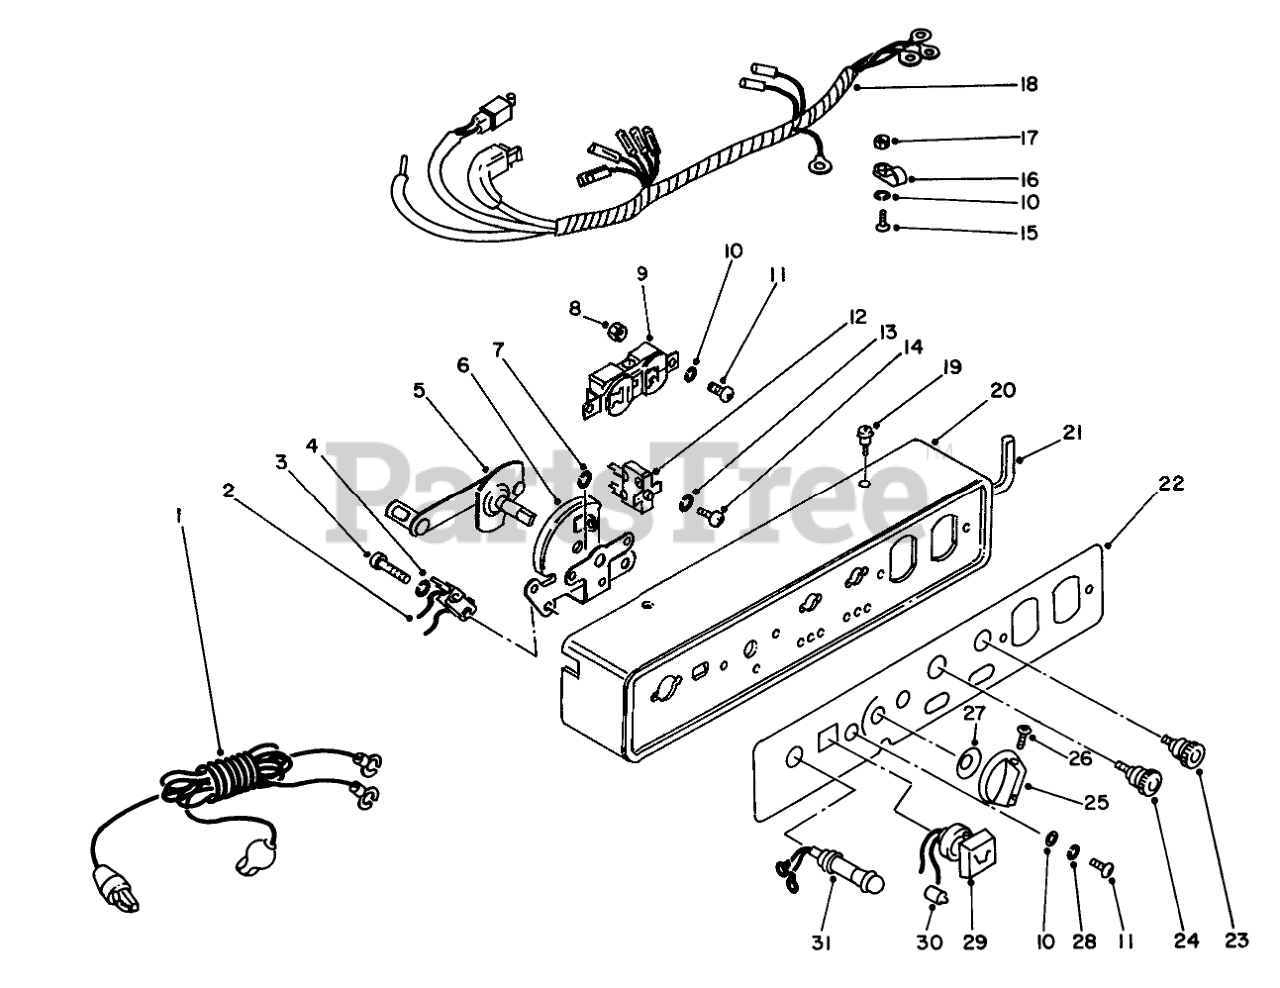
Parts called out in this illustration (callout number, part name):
1	Cord-Charger (optional)
2	Switch-Engine
3	Screw
4	Washer
5	Shaft-Fuel Cock Knob
6	Bracket-Fuel Cock Knob
7	E-Ring
9	RECEPTACLE
10	Washer
11	Screw
12	PROTECTOR
13	Washer
14	Screw
15	Screw
16	Clamp
18	Wiring Harness Control
19	Screw
20	Panel-Control
21	Seal (L:421)
22	Plate-Panel
23	TERMINAL +
24	Terminal (-)
26	Screw
27	Wave Washer
28	Washer-Lock
29	Lamp-Oil Level
31	Holder
